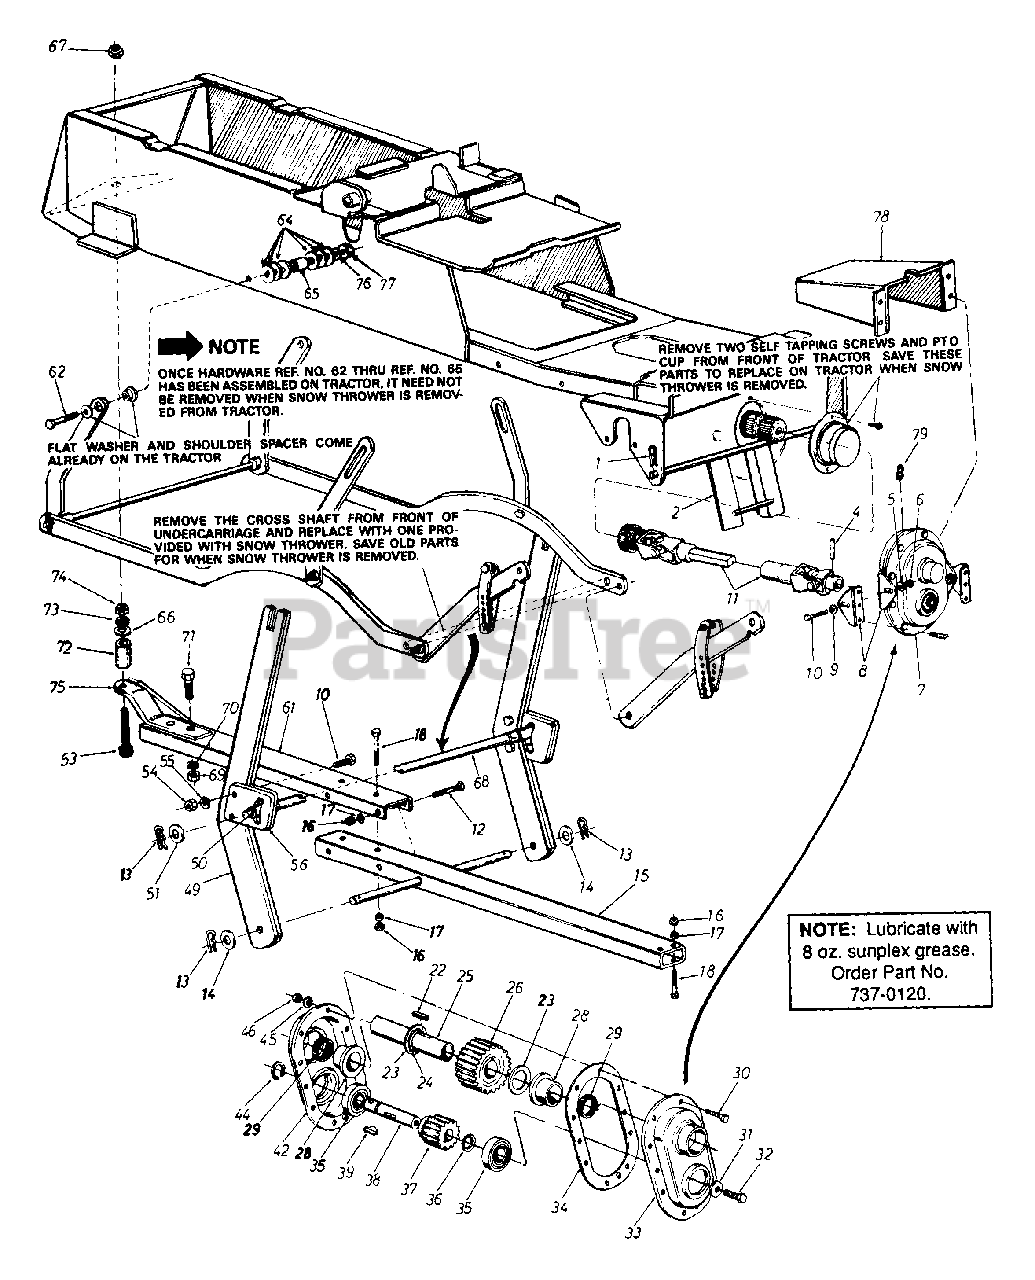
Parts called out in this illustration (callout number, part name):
1	Intern. Cotter Pin 3/4" Dia.
2	Guide Bracket Ass'y.
4	Spring Pin Spiral 5/16" Dia. x 2.5" Lg.
5	Bell-Wash..341" I.D. x .88 O.D.
6	Hex Nut 5/16-18 Thd.
7	Gear Box Ass'y. Comp.
8	Gear Box Support Brkt.
9	Bell-Wash..341" I.D. x.88" O.D.
10	Hex Scr. 5/26-18 x .75" Lg.
11	Universal Drive Shaft Ass'y.
12	Hex Scr. 3/8-24 x 4.50" Lg.
13	Hair Pin Cotter
14	Fl-Wash..62" I.D. x 1.12" O.D.
15	Lift Shaft Ass'y.
16	Hex Ins. Jam L-Nut 3/8-24 Thd.
17	L-Wash. 3/8" Scr.
18	Hex Scr. 3/8-24 x 2.75" Lg.
22	Fl-Wash. 1.31" I.D. x 2.00" O.D. x .060
24	Snap Ring for 1/25" Dia. Shaft
25	Gear Shaft 1.25" Dia. x 6.0" Lg.
26	28 Teeth Spur Gear
28	Flange Brg. 1.25" I.D. x 1.75" O.D.
29	Oil Seal 1.25" I.D. x 1.75" O.D. x .26
30	Hex Scr. 1/4-28 x .88" Lg.
31	Fl-Wash..40 I.D. x 1.25" O.D. x .160
32	Hex L-Scr. 3/8-24 x 1.00" Lg.
33	Compl. Gear Hsg. Half - L.H.
34	Gasket
35	Ball Brg. 1.00" I.D. x 2.00" O.D.
36	Fl-Wash. 1.03" I.D. x 1.63" x .090
37	15 Teeth Spur Gear
38	Input Shaft
39	Woodruff Key 1/4" x 3/4 Dia.
42	Compl. Gear Hsg Half - R H.
44	Snap Ring for 1.00" Dia. Shaft
45	Spring Wash. 1/4" I.D.
46	Hex Nut 1/4-28 Thd.
51	Fl-Wash. 62" I.D. x 1.12" O.D.
53	Hex Bolt 5/8-18 x 4.00" Lg.
54	Hex Nut 5/16-18 Thd.
55	L-Wash. 5/16" Scr.
61	Lift Bracket
62	Hex Scr. 3/8-24 x 2.50"
64	Fl-Wash..375 I.D. x 1.00" O.D. x .135"
65	Spacer .275 I.D. x .625 O.D. x .440
66	Fl-Wash..62" I.D. x 1.12" O.D.
67	Hex Jam L-Nut 5/8-18 Thd.
68	Cross Shaft Ass'y
69	Hex Nut 1/2-13 Thd.
70	L-Wash. 1/2" Scr.
71	Hex Scr. 1/2-13 x 1.25"
72	Bushing
73	L-Wash. 5/8" Scr.
74	Hex Jam Nut 5/8-18 Thd.
77	Hex Nut 3/8-24 Thd.
78	Drive Shaft Cover
79	Grease Fitting
